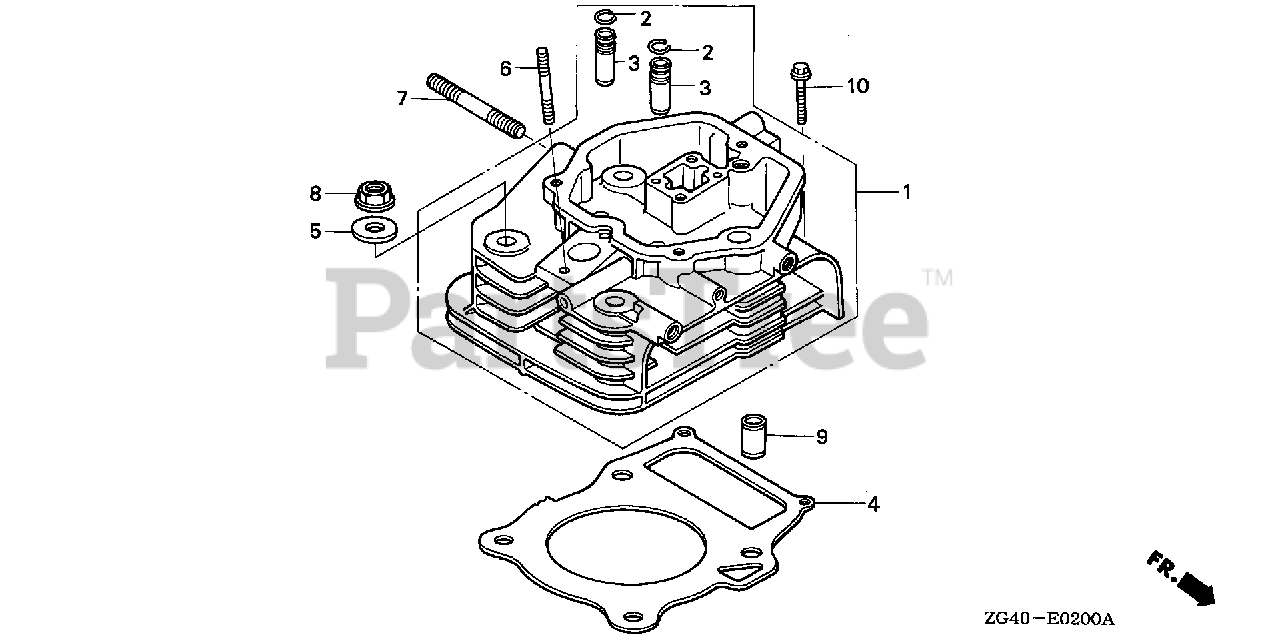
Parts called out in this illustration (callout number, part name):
1	CYLINDER HEAD
2	CLIP, VALVE GUIDE
3	GUIDE, VALVE (OVER SIZE)
4	GASKET, CYLINDER HEAD (1.1) (A)
4	GASKET, CYLINDER HEAD (1.2) (B)
4	GASKET, CYLINDER HEAD (1.3) (C)
5	WASHER (10MM)
6	BOLT, STUD (6X32)
7	BOLT, STUD (8X28)
8	NUT, FLANGE (10MM)
9	PIN, DOWEL (12X20)
10	BOLT, FLANGE (6X28)
